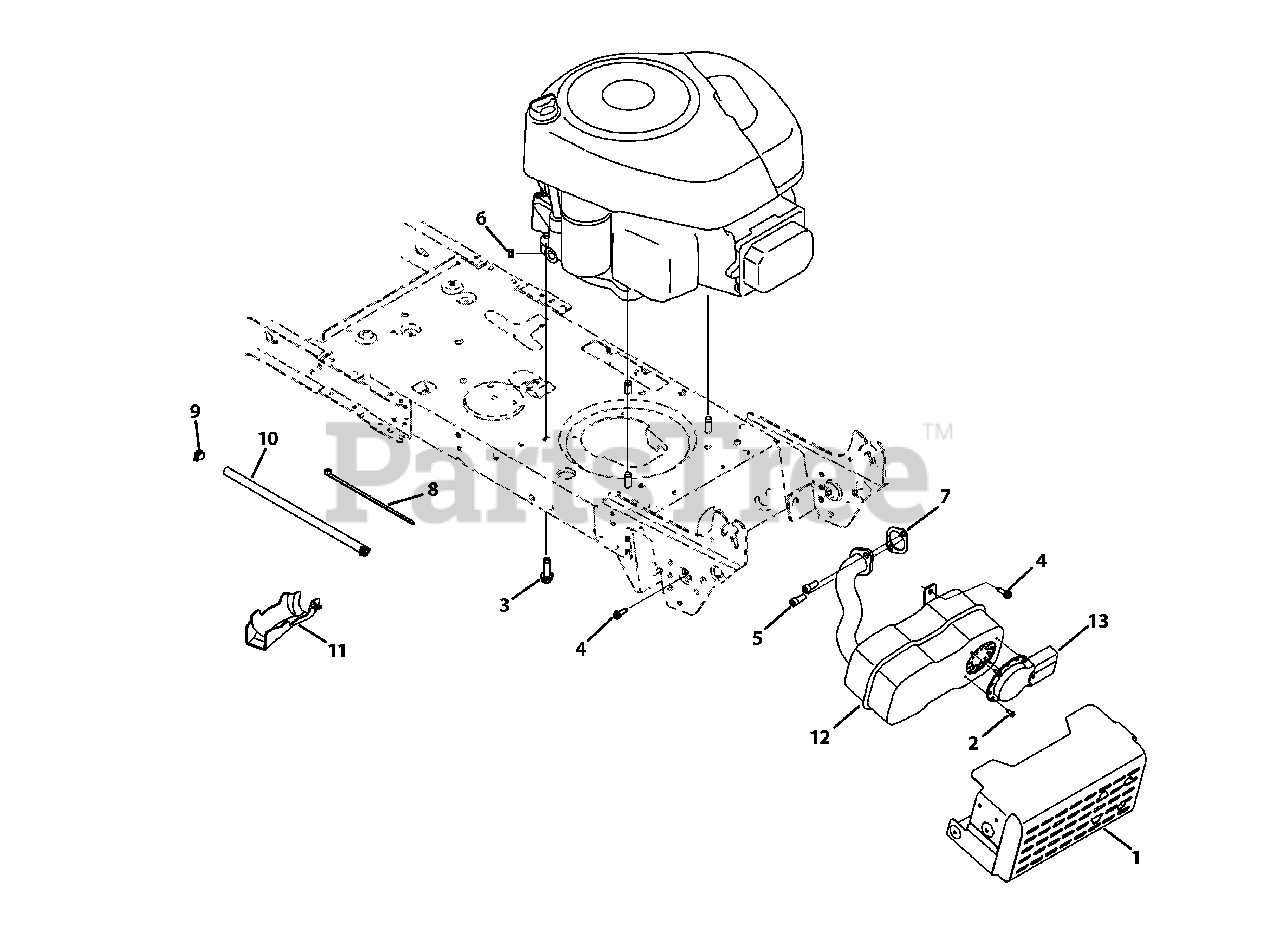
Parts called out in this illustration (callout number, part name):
1	Muffler Shield Assembly
2	Screw, 8-18 x .500
3	Screw, 3/8-16 x 1.0
4	Screw, 1/4-20 x .750
5	Socket Screw, 5/16-18 x .750
6	Sems Nut, 1/4-20
7	Exhaust Gasket, 10 HP Briggs
8	Cable Tie
9	Clamp Hose, .490 diameter
10	Fuel Hose, Low Permeation
11	Oil Drain Sleeve
12	Muffler, Single Inlet
13	Muffler Deflector Long
